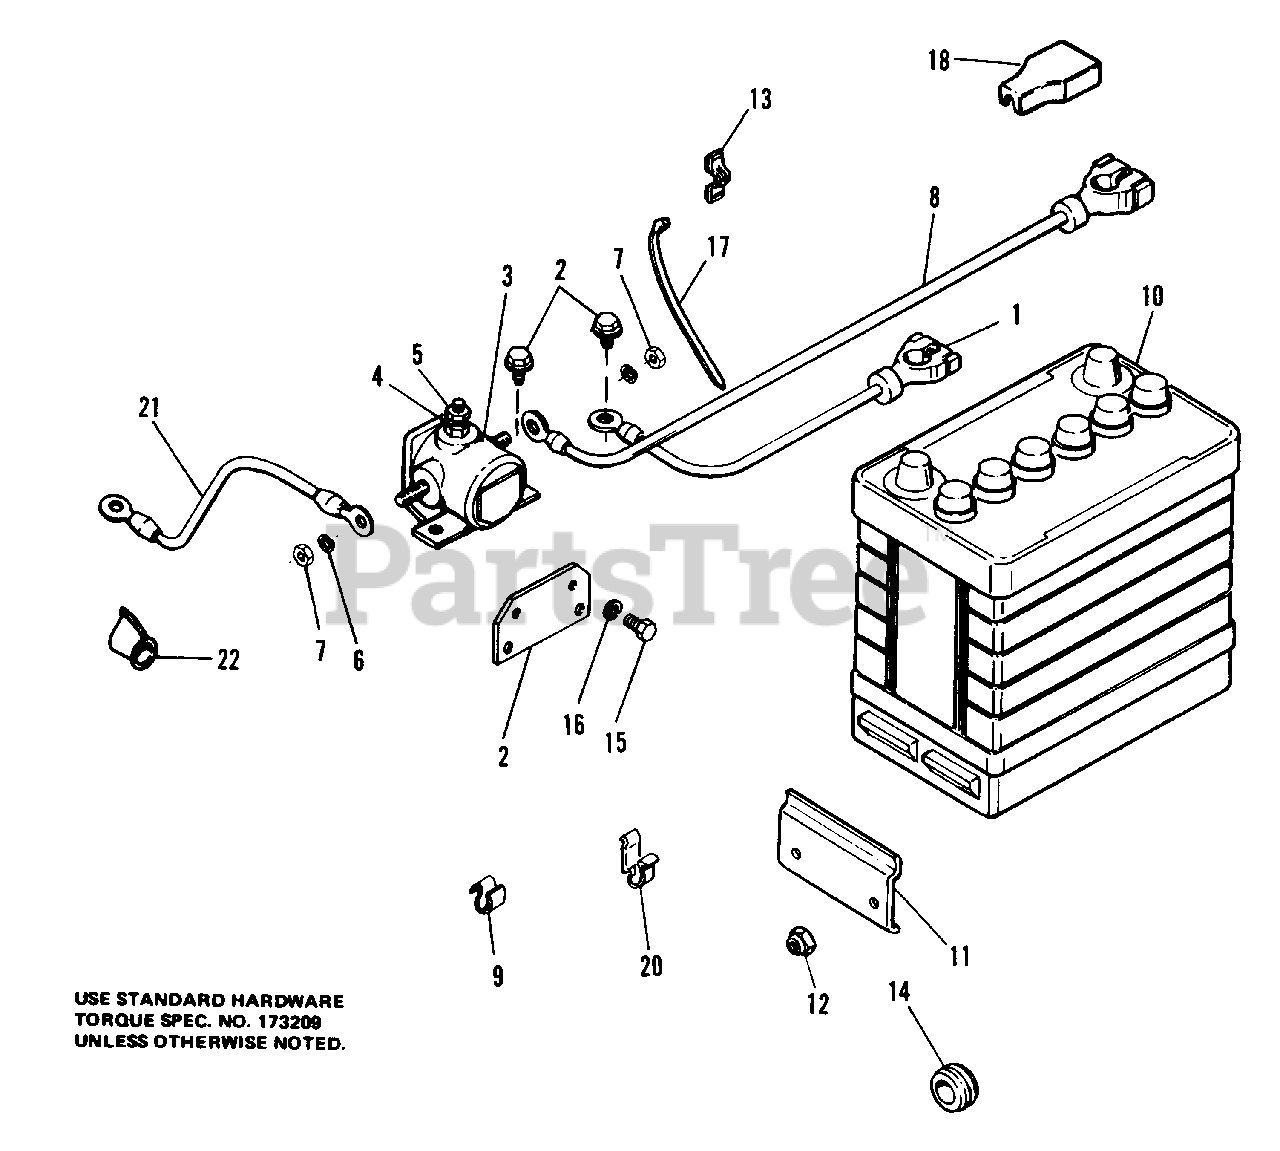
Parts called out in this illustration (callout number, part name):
1	CABLE, Battery to Ground
4	LOCKWASHER, No. 10
5	NUT, Hex, No. 10-32
6	LOCKWASHER, 5/16
7	NUT, Hex, 5/16-18
8	CABLE, Battery to Solenoid
9	CLIP, Tinnerman
12	NUT, Elastic, 5/16-18
13	CLIP, Wire
15	CAPSCREW, Hex Hd., 1/4-20 x 1/2
16	LOCKWASHER, 1/4
17	TIE, Wrap
18	TERMINAL PROTECTOR
19	SCREW, Taptite, 1/4-20 x 1/2
20	CLIP, Tinnerman
21	CABLE, Solenoid to Start
22	COVER, Terminal
